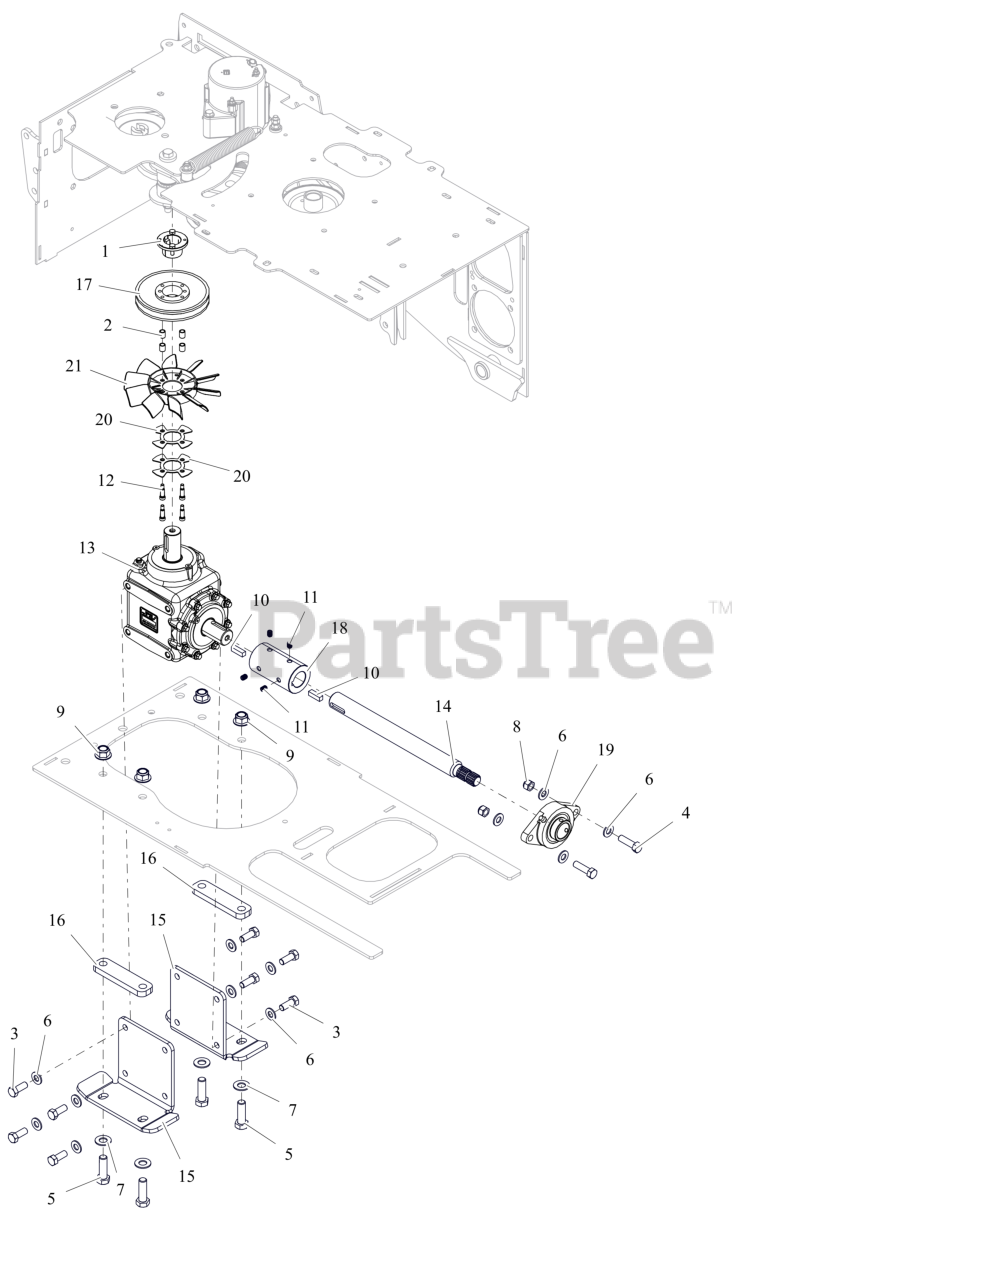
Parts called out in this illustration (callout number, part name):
1	BUSHING- PULLEY SPLIT TAPER
2	BSHG-SLV .330X.455X.550
3	BLT,HEX .50-13X1.25 G5 ZCC
4	BLT, HEX .50-13X1.75 G5 ZCC
5	BOLT, HEX 0.625-11X2 GR5
6	WSHR,FLT .531X1.062X.095 ZCC
7	WSHR, FLT .656X1.313X.095 ZCC
8	NUT,NYL .50-13 G5 ZCC
9	NUT,NYL-FLG .63-11 GF ZCC
10	KEY-SQ .38X1.25X.375
11	SCR-SET-.375-16X.50 SKH
12	BLT-SHLDR .313X.750X.25-20
13	GEARBOX- 90DEG VR COMMERICAL
14	SHAFT- PTO INTERMEDIATE
15	PLATE- MOUNT GEARBOX
16	PLATE- SPCR - GEARBOX
17	PULLEY- GEARBOX BK62H
18	COUPLING- SHAFT
19	BRG- FLANG 2 BOLT
20	BRKT, FAN
21	FAN, COOLING - PARKER
